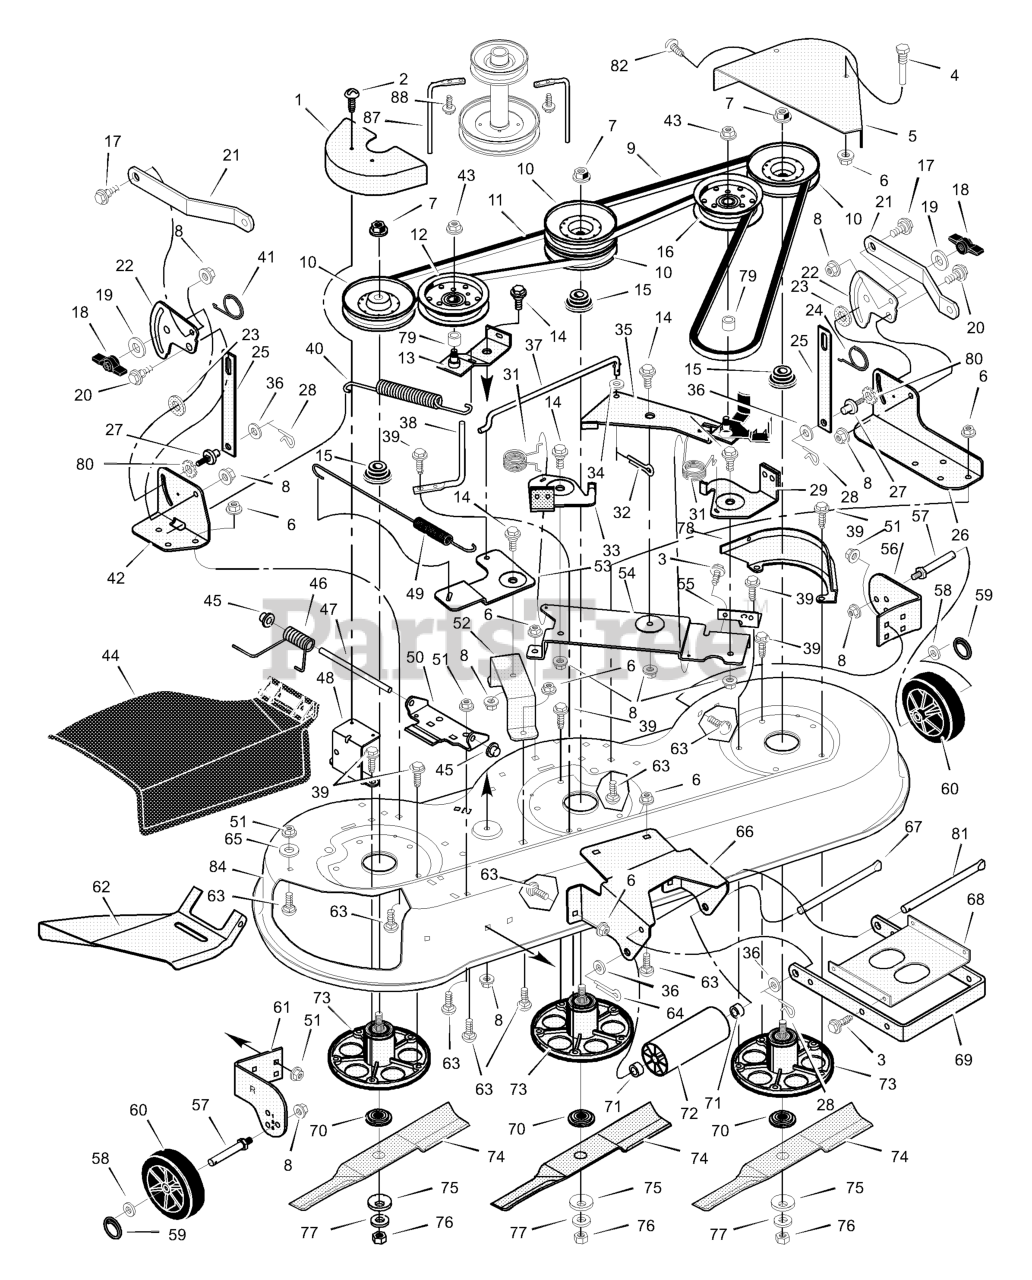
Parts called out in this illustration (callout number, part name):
1	Cover, Right Pulley
2	Screw
4	Guide, Belt
5	Cover, Left Pulley
6	Nut, Hex
7	Nut, Flange
8	Nut, Flange
9	Belt, Primary
10	Pulley
11	Belt, Secondary
12	Pulley, Idler
13	Arm, Idler
14	Bolt, Shoulder
15	Spacer, Pulley
16	Pulley, Idler
17	Bolt, Shoulder
18	Knob
20	Bolt, Shoulder
21	Bracket, Rear Suspension
22	Plate, Suspension
23	Pad, Friction
25	Link, Lift
26	Bracket, Left Lift
27	Pin, Hanger
28	Pin, Hair
29	Brake Assembly, Left
32	Pin, Cotter
33	Brake Assembly, Right
34	Washer
35	Idler, Arm
37	Link, Bell Crank
38	Guide, Belt
39	Screw
40	Spring, Extension
41	Spring, Torsion
42	Bracket, Suspension
43	Nut
44	Deflector, Chute
45	Push On Cap
46	Spring, Torsion
47	Rod, Deflector
48	Bracket, Cover
49	Spring, Extension
50	Bracket, Hinge
51	Nut, Flange
52	Bracket, Bell Crank
53	Crank, Bell
54	Plate, Brake Arm
55	Bracket, Brake Plate
56	Bracket, Left Gauge Wheel
57	BOLT, Gauge Wheel
59	Ring, Locking
60	Wheel, Gauge
61	Bracket, Right Gauge Wheel
62	Deflector, Inside
63	Bolt, Carriage
64	Pin, Cotter
66	Bracket, Front Deck
67	Rod, Hanger
68	Stiffener
69	Bracket, Suspension
70	Adapter, Blade
73	Housing, Jackshaft
75	Washer, Belleville
78	Bracket, Pulley Cover
81	Rod, Hanger
84	Housing, Blade
87	Guide, Belt
88	Screw
